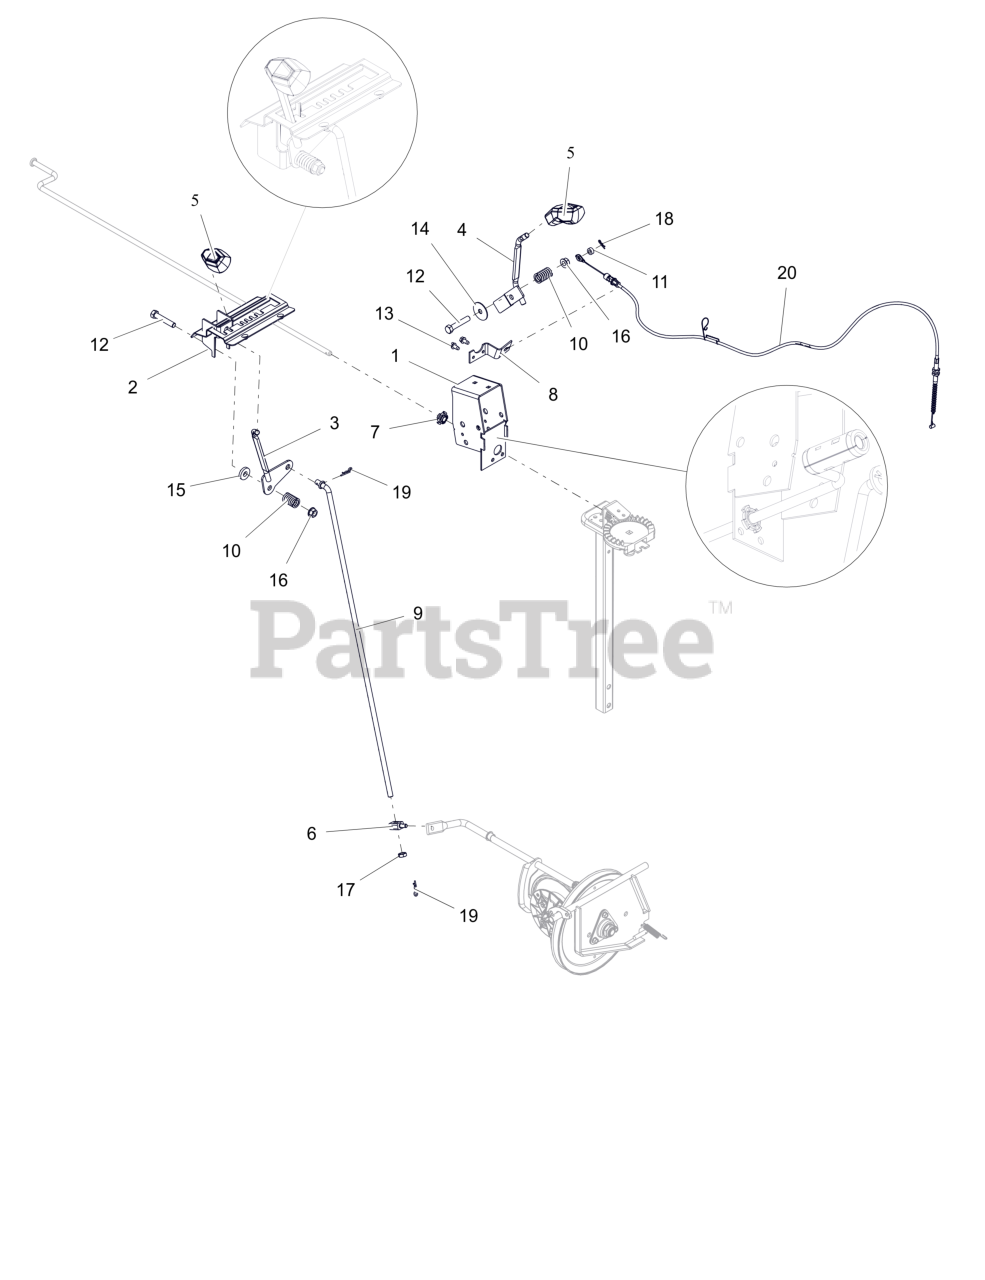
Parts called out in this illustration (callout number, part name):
1	WELDMENT, BRACKET INTERLOCK
2	WELDMENT, DETENT PLATE-COMPACT
3	LEVER, CONTROL-SHIFT(WELDMENT)
4	WELDMENT,SM DASH DEFL CONTROL
5	KNOB, CONTROL
6	PIVOT,SHIFT ROD .375-16(TRUNN)
7	CRANK BUSHING, NYLON CHUTE BK
8	ANCHOR, DEFLECTOR CABLE
9	ROD, SHIFT - COMPACT
10	SG-COMP .125X.781X1.250
11	BSHG-SLV .265X.500X.219
12	BLT,HEX .38-16X2.00 G5 ZCC
13	SCR-TAP .25-20X.50 HWH ZCC
14	WSHR,FLT .380X1.50X.062 ZCC
15	WSHR, FLT .406X1.00X.188 ZCC
16	NUT-LK-TOP-FLG .38-16 ZC120
17	NUT-JAM .375-16 G2 ZCC
18	PIN, HAIR #178 .06X.77 ZCC
19	PIN, HAIR #213 .08X1.19 ZCC
20	CABLE, DEFLECTOR - COMPACT
